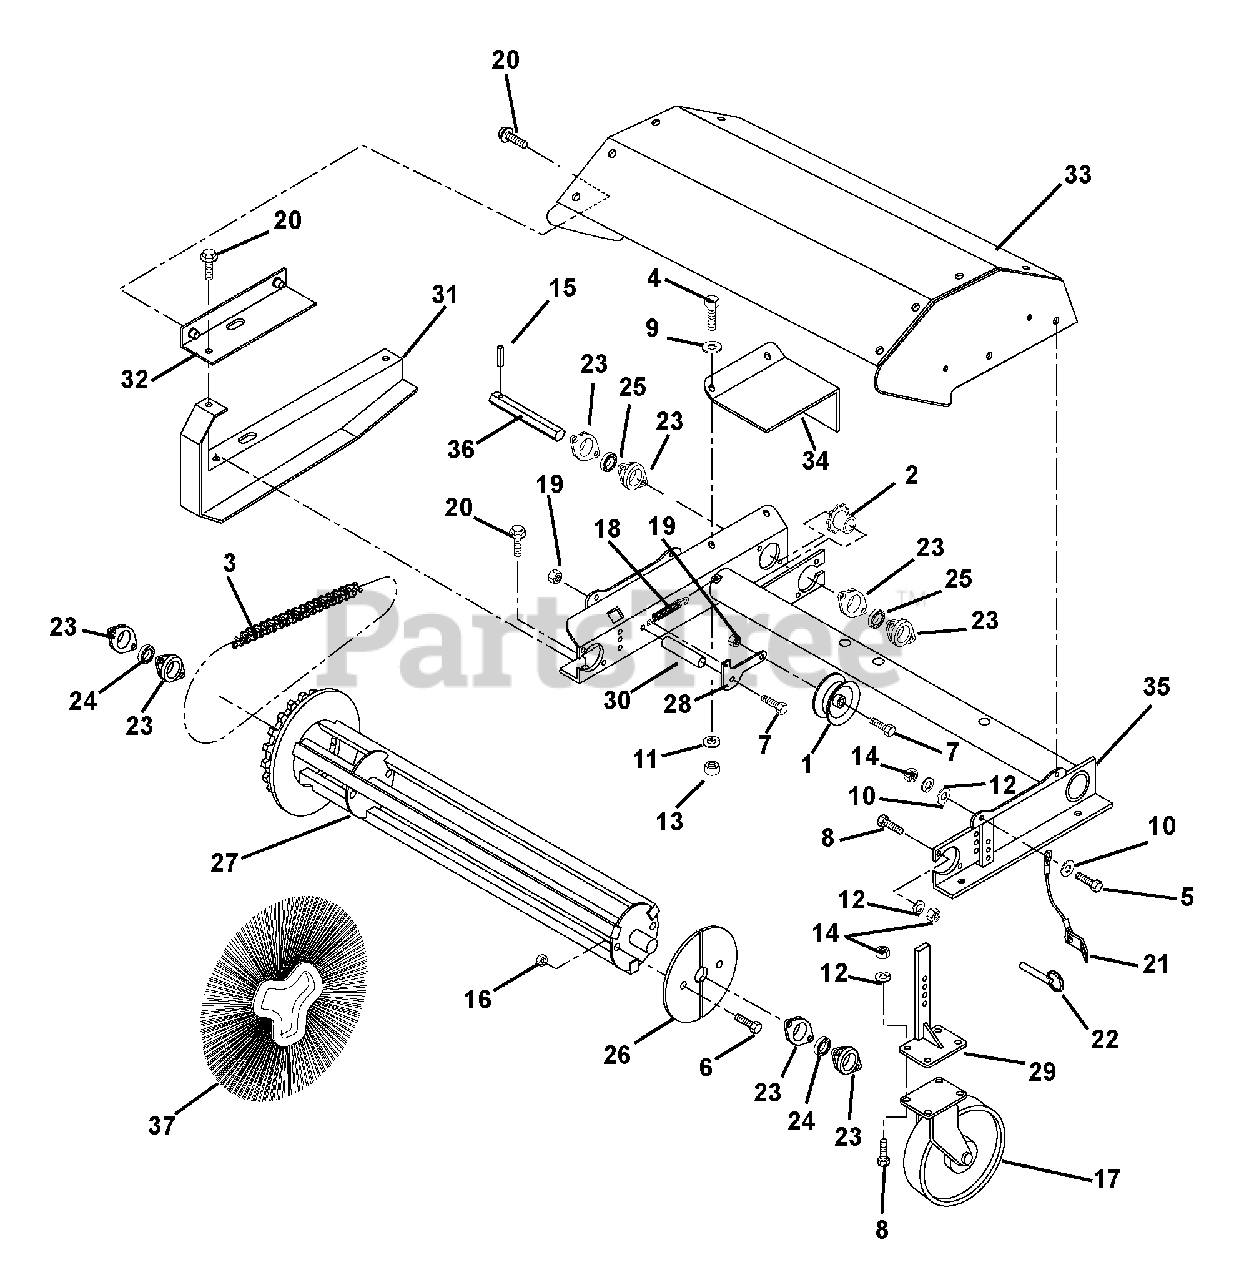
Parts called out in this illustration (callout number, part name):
1	CHAIN TIGHTENER
2	SPROCKET
3	CHAIN, ASS'Y #40X106 EDLS W/LK
4	@BLT-HEX .25-20X.75 GR5 YWZC
5	@BLT-HEX .31-18X1.00 GR5 YWZC
6	@BLT-HEX .31-18X2.25 GR5 YWZC
7	@BLT-HEX .38-16X1.50 GR5 YWZC
8	@BLT-HEX .31-18X.75 GR5 YWZC
9	@WSHR-FL-STL.281X.62X.065 YWZC
10	@WSHR-FL-STL.312X.734X.065 YWZ
11	@WSHR-LK .25X.062 REG YWZC
12	@WSHR-LK .31X.078 REG YWZC
13	@NUT-HEX .25-20 YWZC
14	@NUT-HEX .31-18 YWZC
15	PIN, SPRING LOK .187 X 1.25
16	NUT, LOK STAMPED .312-18 TINN.
17	WHL, 5 DIA.
18	SPRING, TENSION .50 X 3.0
19	@NUT-LK-CTR .38-16 YWZC
20	SCREW, GR 10.9 M6X1-20
21	LANYARD,.06 CAB.1.25X6,TYP C
22	PIN, HITCH, .38 X 2
23	FLANGE, SPHERICAL 2"
24	BRG 1.00 BORE, SPHER. OD.
25	BRG-BALL .884HEXX52MMX1.07
26	RETAINER PLATE (SET OF 2)
27	WELD, CORE C36TW
28	ARM, IDLER,BRM C36TW
29	WELD, CASTER LEG, C36TW
30	BSHG, .62X12 GA X.75
31	SHIELD,CHAIN, ARIENS
32	SHIELD, CHAIN,TOP,ARIENS
33	KIT, HD, ARIENS
34	SHIELD, INPUT, ARIENS
35	WELD, BFRM,ARIENS
36	SHAFT, HEX 20.5, W/HOLE
37	SET,SECTION,24",P,CONV.
